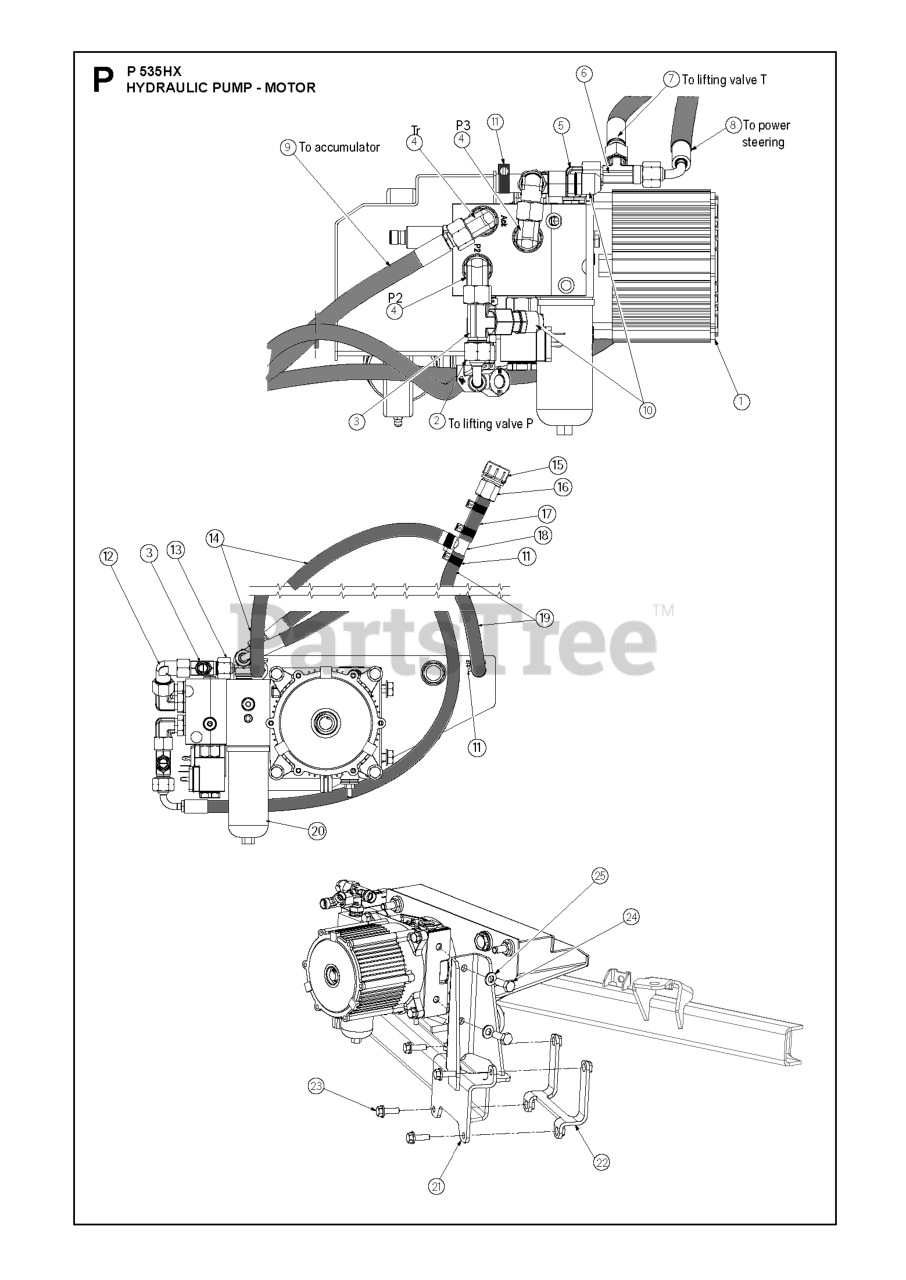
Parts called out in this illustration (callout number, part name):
11	HOSE CLAMP FUEL HOSE
23	BOLT
24	Screw M10x25
25	WASHER
